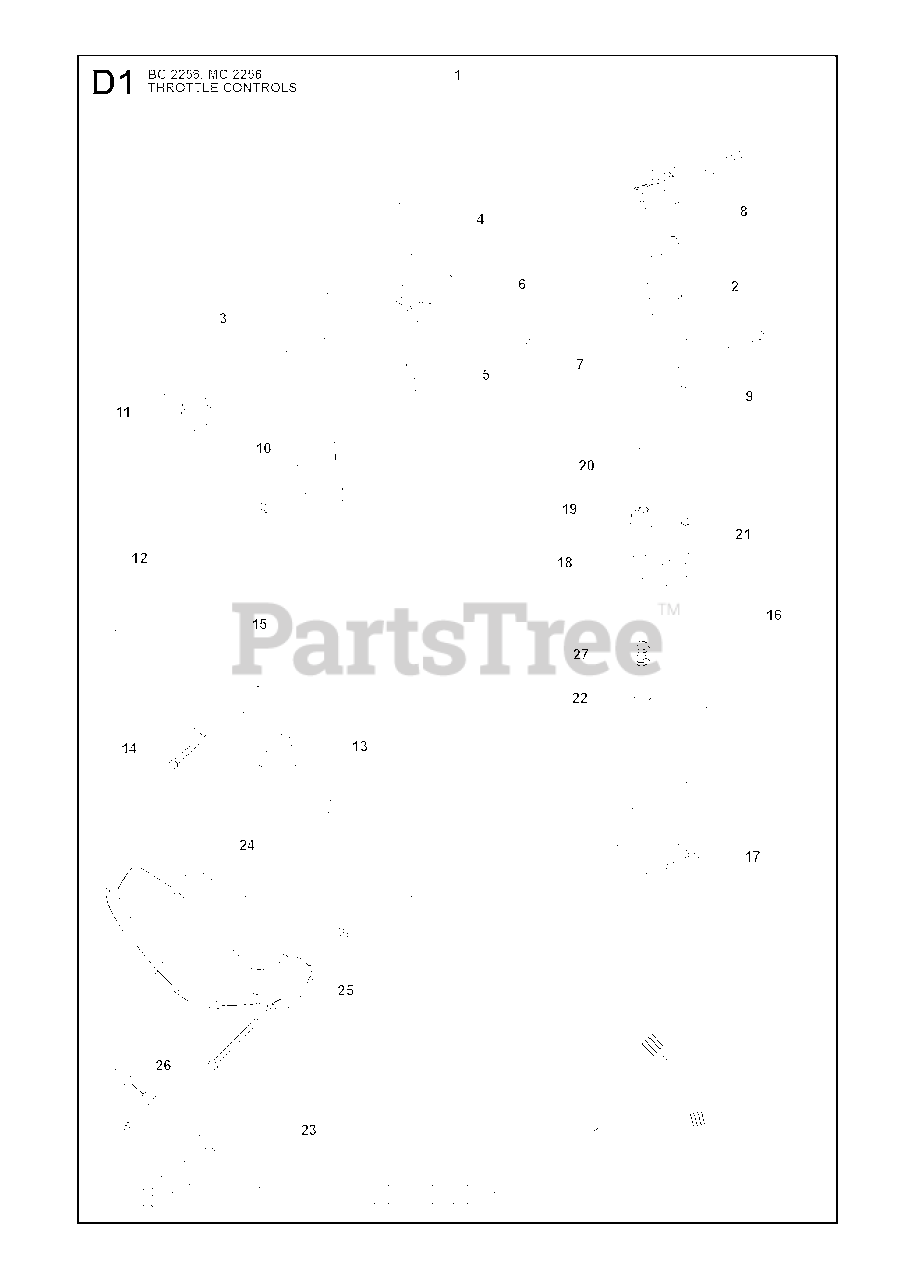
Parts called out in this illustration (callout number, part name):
1	THROTTLE HANDLE ASSY
2	HANDLE HALF RIGHT
4	SWITCH
5	THROTTLE CONTROL
6	SPRING
7	SPRING
8	SCREW
9	%SCREW
10	NUT
11	STOP BUTTON
15	NUT M6M M5
16	HANDLE
17	HANDLE BRACKET
18	HANDLE BRACKET
20	SCREW 6X70
